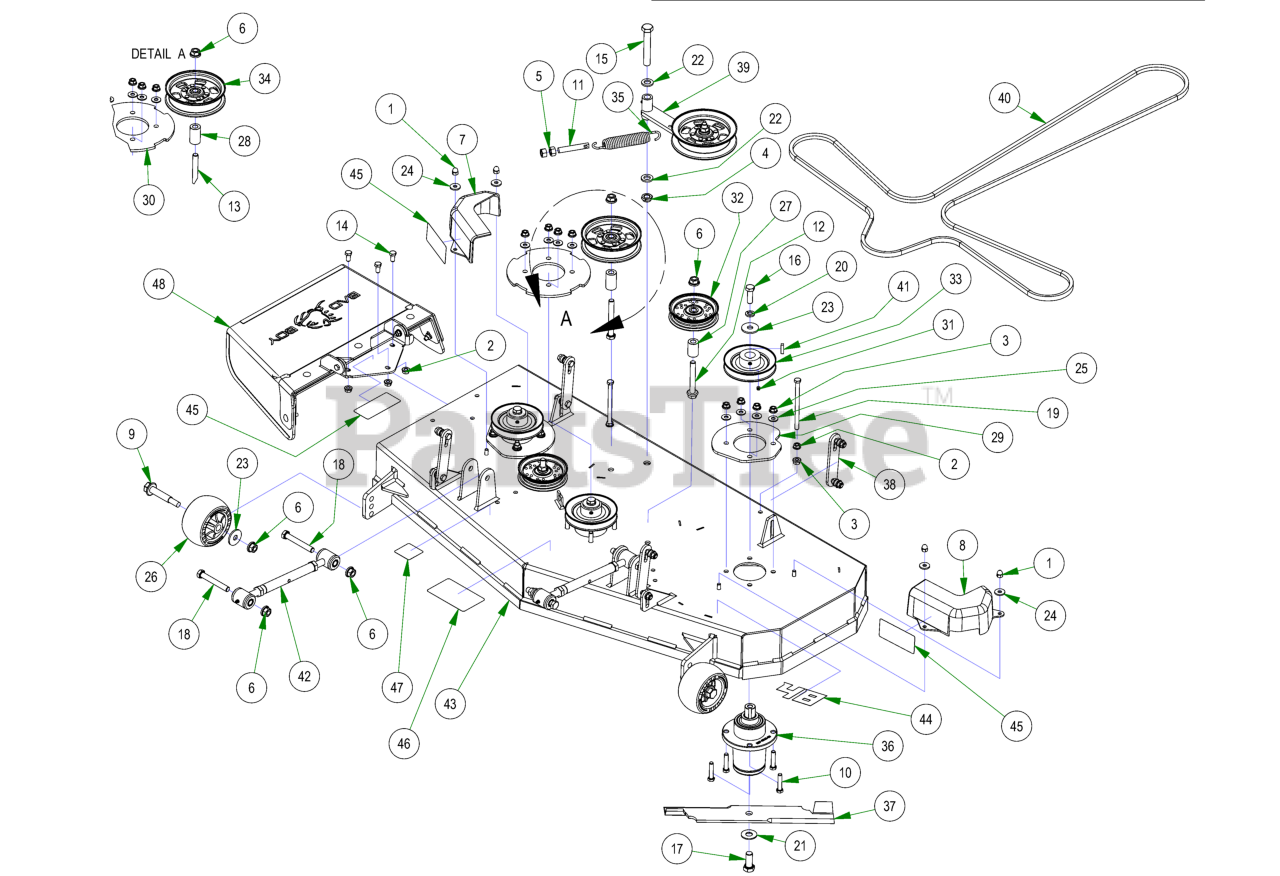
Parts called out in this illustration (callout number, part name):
1	5/16-18 ACORN NUT HIGH-CROWN ZC
2	3/8-16 HEX SERRATED FLANGE NUT HARD/ZINC
3	3/8-16 NYLON INSERT FLANGE LOCKNUT (GR.F) ZINC
4	5/8-11 NYLON INSERT JAM LOCKNUT ZINC
5	1/2-13 HEX NUT ZINC
6	1/2-13 NYLON INSERT FLANGE LOCKNUT ZINC
7	pulley cover chute side
8	pulley cover non-chute side
9	Deck Wheel Bolt
10	3/8-16 X 1-3/4 HEX C/S (GR.5) ZC
11	All Thread
12	1/2-13 X 3-1/2 HEX FLANGE BOLT (GR.8) ZINC
13	1/2-13 X 4 HEX CAP SCREW (GR.8) ZINC YELLOW
14	3/8-16 X 3/4 HEX CAP SCREW (GR.5) ZINC
15	5/8-11 X 4 HEX CAP SCREW (GR.8) ZINC YELLOW
16	1/2-20 X 1-1/2 HEX CAP SCREW (GR.5) ZINC
17	5/8-18 X 1-1/2 HEX CAP SCREW (GR.8) ZINC YELLOW
18	1/2-13 X 3-1/2 HEX CAP SCREW (GR.5) ZINC
19	3/8-16 X 5-1/2 HEX CAP SCREW (GR.5) ZINC
20	1/2 SPLIT LOCKWASHER (GR.8) ZINC/YELLOW
21	5/8 USS FLAT WASHER (1-3/4" OD) GR.8 ZINC YELLOW
22	.635 ID X 1.120 OD X .140 THICK FLAT WASHER NYLON
23	1/2 BELLEVILLE WASHER (1-5/8 OD X .140 THK) ZINC
24	.360 ID X .983 OD X .120 THICK FLAT WASHER NYLON BLACK
25	5/16 USS FLAT WASHER (7/8 OD) ZINC
26	Deck Wheel
27	.502 ID X .750 OD X 1.500 Long Spacer
28	1 3/4" Pulley Spacer
29	42&48 Deck Spindle Support Plate
30	Deck Spindle Support Plate
31	5/16-24 X 1/4 SOCKET SET SCREW (CUP PT) PLAIN
32	4 3/4 Idler Pulley - ABFI-76
33	5" Spindle Deck Pulley
34	5-3/4 Idler Pulley
35	Deck Idler Spring
36	Spindle Assembly
37	48" ZT/Mav/Compact Outlaw Blade with Fusion
38	Deck Hanger Assembly
39	2017 MZ/ZT Deck Idler Assembly
40	B147 Deck Belt
41	1/4 X 1 SQ MACHINERY KEY 1018 STL PLN
42	2018 Maverick Turnbuckle (Top Link)
43	2023 48" x 5" Deck
44	48" Deck Decal
45	Danger Decal-Spindle/Discharge
46	Deck Belt Route Decal
47	Deck Impact Patent Decal 9591803
48	ZT Chute Assembly
